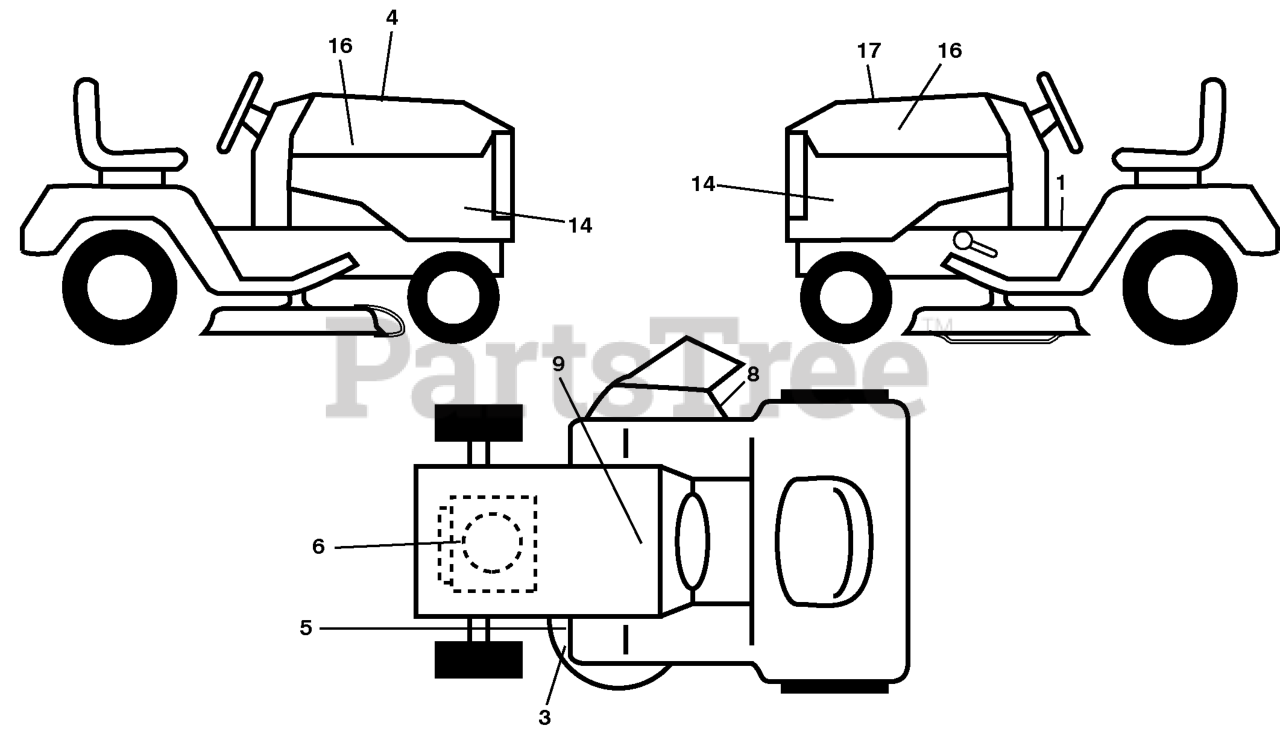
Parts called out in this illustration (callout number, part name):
1	DECAL.FENDER.WARNING.ENG
3	DECAL.WARN.KEEP.HAND.AWAY
4	DECAL.WARNING.CUST.RESP.E85.
5	DECAL.MOWER
6	Decal, Eng. HP
8	DECAL.MOWER.SCH.48/54
9	DECAL BTRY SYMBOLS
14	DECAL SDPNL.YTH24V54.B&S.HUSQ
16	RP.DECAL.BADGE.170MM.TEXTLOGO
17	Decal, Replacement
